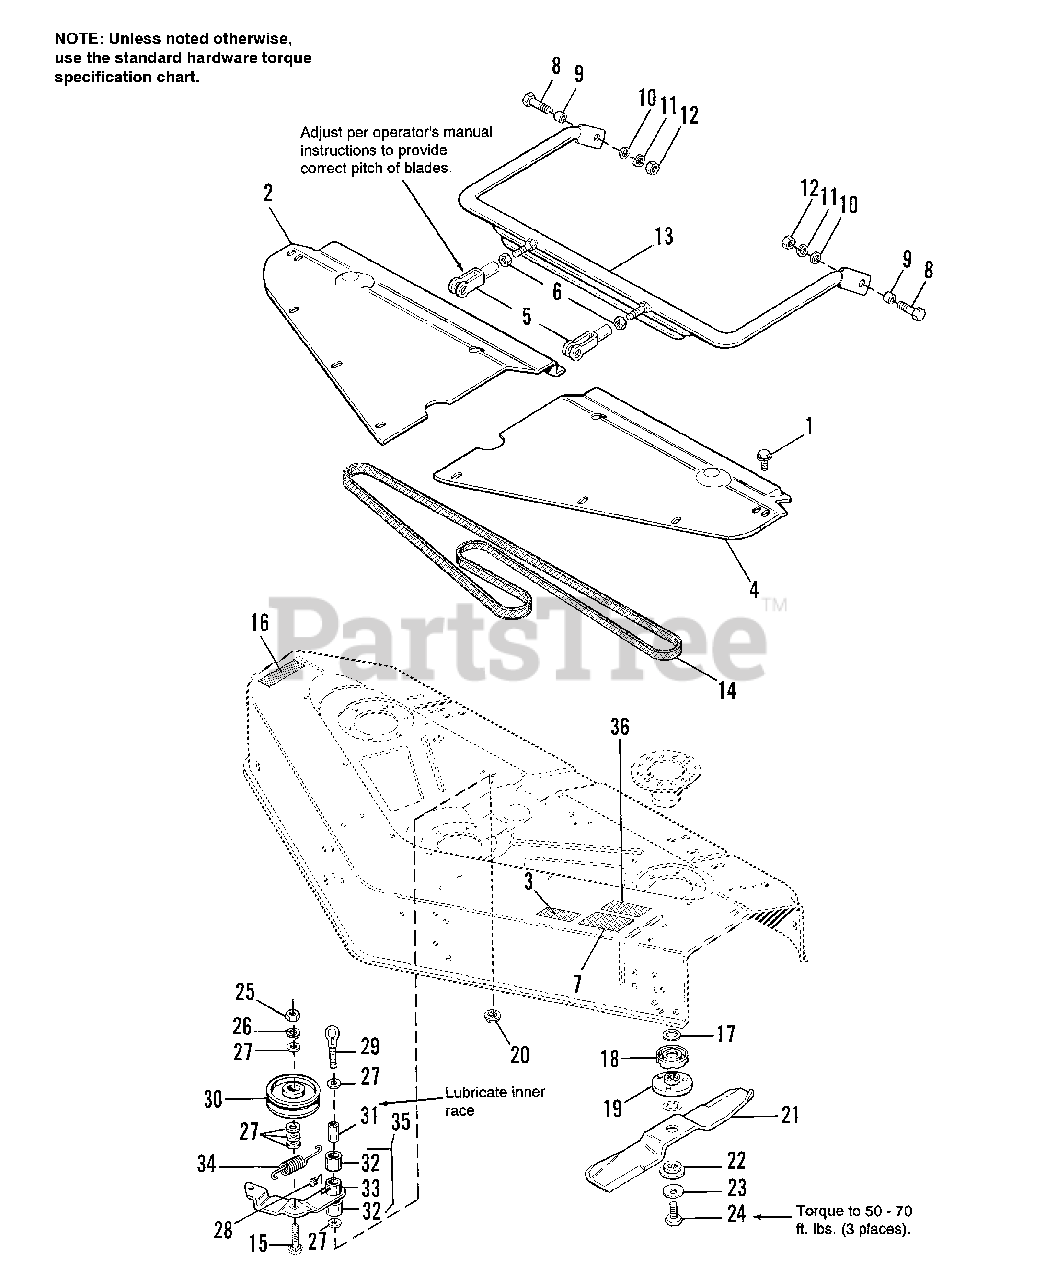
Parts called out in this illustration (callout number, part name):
1	CAPSCREW, Hex Hd, Taptite, 1/4-20 x 3/8
2	COVER, R.H. (Orange)
2	COVER, R.H. (Black)
3	DECAL, Belt Installation, Adjustment
4	COVER. L.H. (Orange)
4	COVER. L.H. (Black)
6	NUT, Hex, Jam, 1/2-20
7	DECAL, Danger, Deflector in place
8	CAPSCREW, Hex Hd, 1/2-13 x 1-1/4
10	WASHER, Plain, 7/16
11	LOCKWASHER, 1/2
12	NUT, Hex, Full, 1/2-13
13	BAIL ASSEMBLY
14	BELT, "V", Arbor Drive
15	CARRIAGE BOLT, 3/8-16 x 1-1/4
16	DECAL, Danger, Rotating Blade
17	WASHER, Shim
18	SHIELD, Grass
19	ADAPTOR, Blade
20	NUT, Hex Flange, Whiz Lock, 3/8-16
21	BLADE, 48" Mower
22	WASHER, Spline
23	WASHER, Spring
24	CAPSCREW, Hex Hd., 7/16-14 x 1-1/4
25	NUT, Hex, Jam, 3/8-16
26	LOCKWASHER, 3/8
27	WASHER, Plain, 13/32
28	FITTING, Lube, 1/4 - 28
30	PULLEY ASSEMBLY, Idler
35	LEVER ASSEMBLY, Idler
36	DECAL, Cutting Width, 48"
